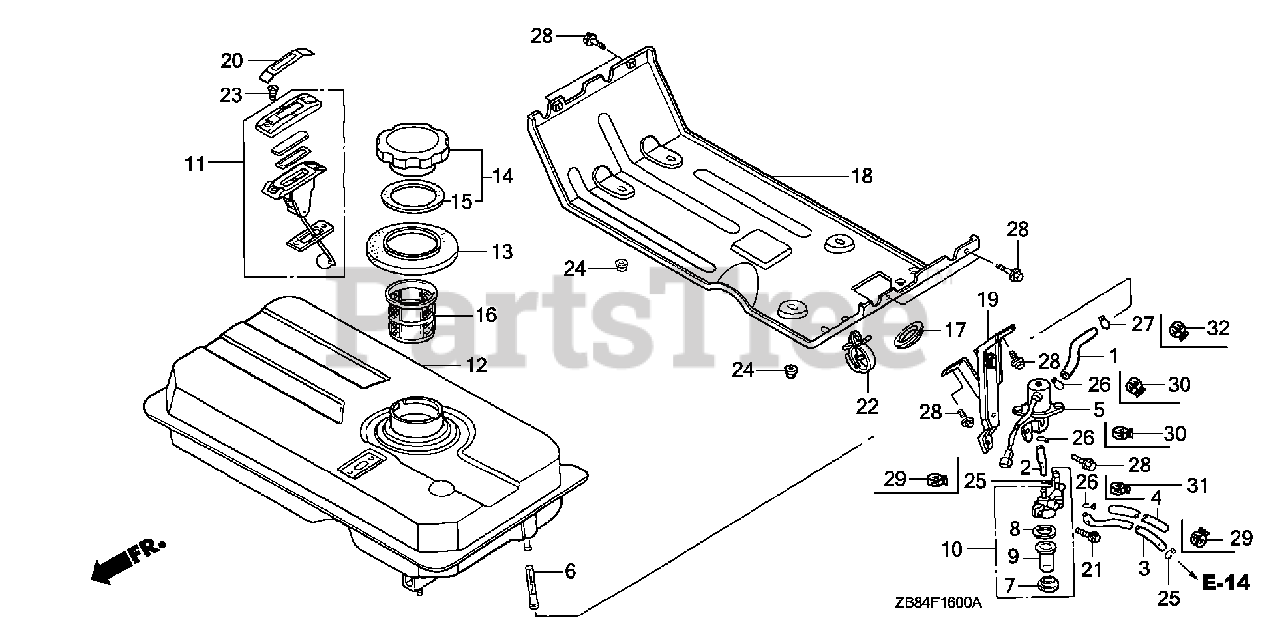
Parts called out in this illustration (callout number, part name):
1	TUBE, FUEL (TANK-VALVE)
2	TUBE, FUEL (VALVE-STRAINER)
3	TUBE, FUEL (STRAINER-CARBURETOR)
4	TUBE, FUEL SUPPORTER
5	VALVE ASSY., ELECTRIC FUEL
6	FILTER, FUEL
9	CUP, FUEL STRAINER
10	CUP ASSY., FUEL STRAINER
11	METER ASSY., FUEL
12	TANK, FUEL
13	SEAL, FUEL FILLER NECK
14	CAP, FUEL FILLER
15	GASKET, FUEL FILLER CAP
16	FILTER, FUEL
17	GROMMET, WIRE
18	PLATE, FUEL TANK HANGER
19	BRACKET, STRAINER CUP SETTING
21	BOLT, FLANGE (5X12)
22	CLIP, HARNESS
23	SCREW, FLAT (5X10)
24	NUT, FLANGE (6MM)
25	CLIP, TUBE (B8)
26	CLIP, TUBE (B10)
27	CLIP, TUBE (B12)
28	BOLT, FLANGE (6X12)
